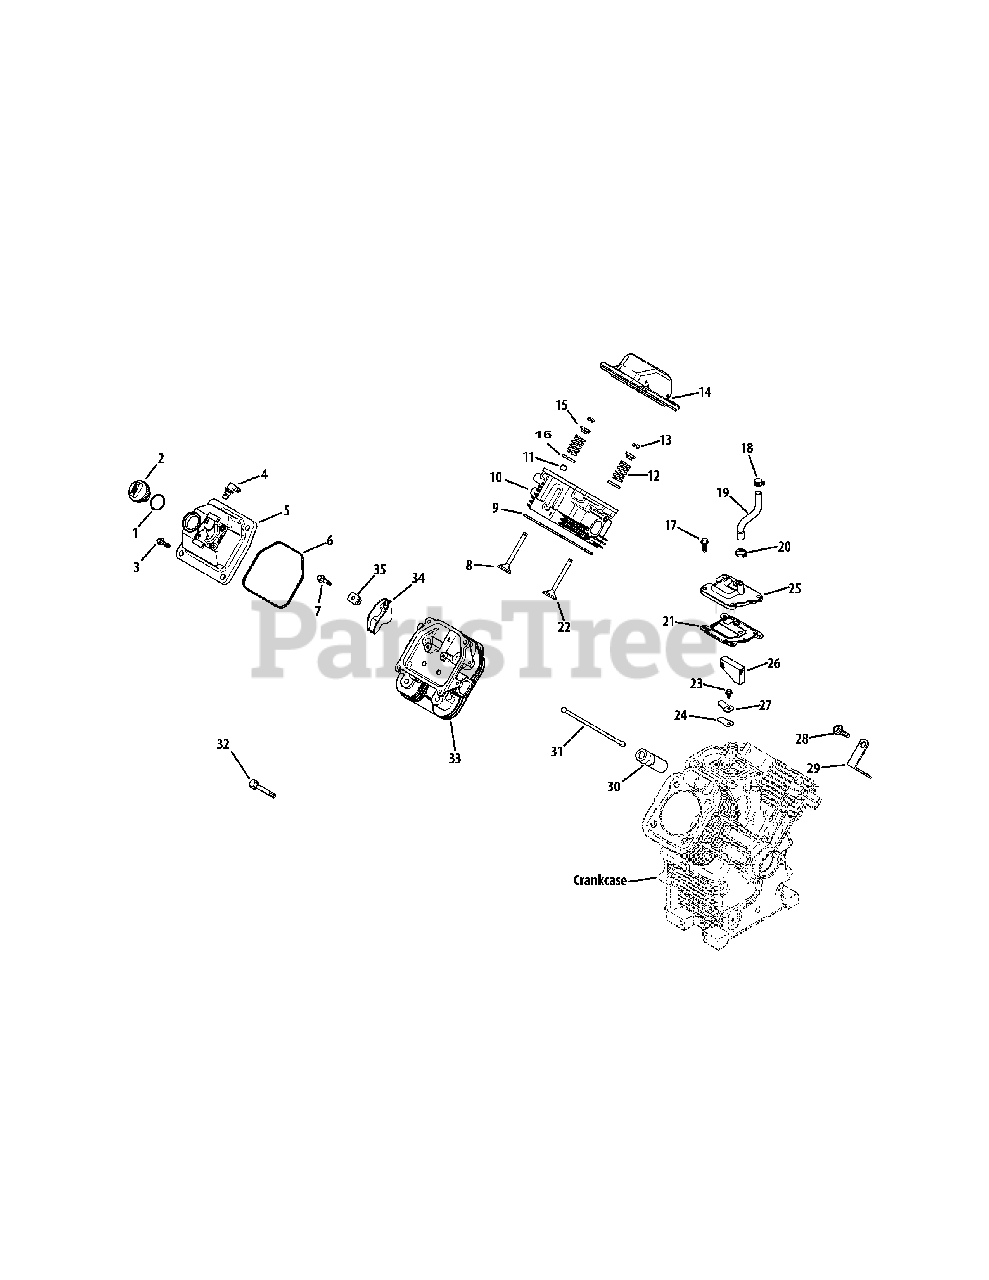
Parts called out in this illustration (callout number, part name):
2	Oil Fill Cap Assembly
3	Flange Screw, M6 x 1.0 x 30
4	90 Degree Fitting Kit
5	Valve Cover-Fuel Pump Kit
6	Vlave Cover O-Ring
7	Flange Screw, M6 x 1.0 x 34
8	Exhaust Valve (Std)
8	Exhaust Valve (.25)
9	Cylinder Head Gasket Kit (C17-22)
10	#1 Cylinder Head Assembly Kit
11	Valve Stem Seal
12	Valve Spring
13	Retainer Kit
14	Valve Cover-Plain Kit
15	Valve Spring Cap
16	Spring Retainer
17	Thread Forming Screw
18	Band Spring Hose Clamp
19	Breather Hose
20	Hose Clamp (KM)
21	Breather Gasket
22	Intake Valve (Std)
22	Intake Valve (.25)
23	Flange Thread Forming Screw,M5 x .8 x 10
24	Breather Reed
25	Breather Assembly Kit
26	Breather Filter
27	Reed Retainer
28	Thread Forming Screw
30	Hydraulic Valve Lifter
32	Flange Screw, M10 x 1.5 x 90
33	#2 Cylinder Head Assembly Kit
34	Valve Train Kit
35	Rocker Arm Pivot
